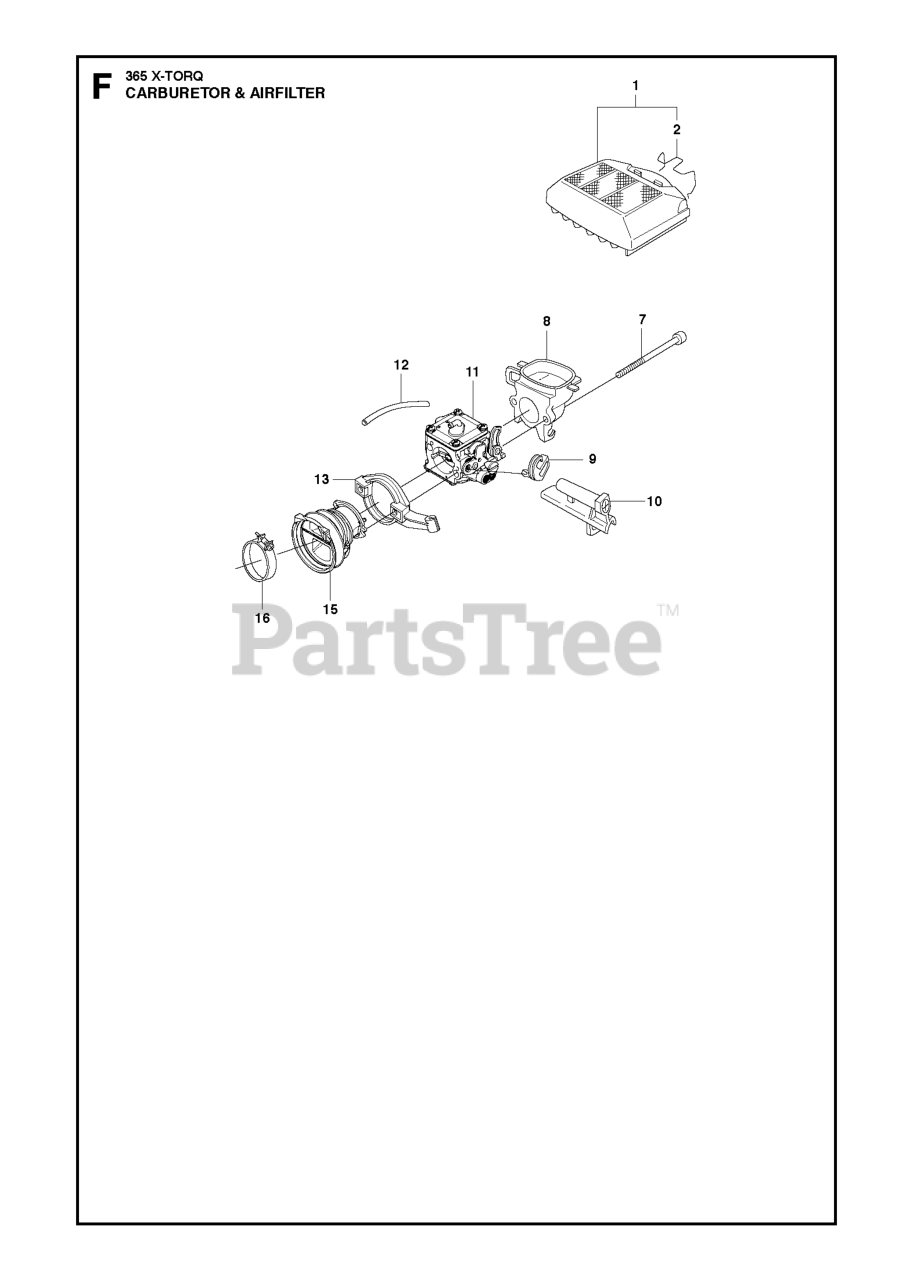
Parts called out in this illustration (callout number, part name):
1	AIR FILTER ASSY
2	AIR FILTER CLIP
7	SCREW ITXSCM M4X70 T20 12.9 TB
8	FILTER HOLDER STANDARD FILTER
10	GUIDE SLEEVE CARB
11	CARBURETTOR RWJ-4B
15	INLET PIPE (FOR COLD)
15	INLET PIPE
16	HOSE CLAMP JALMARSON-MPC MINI
